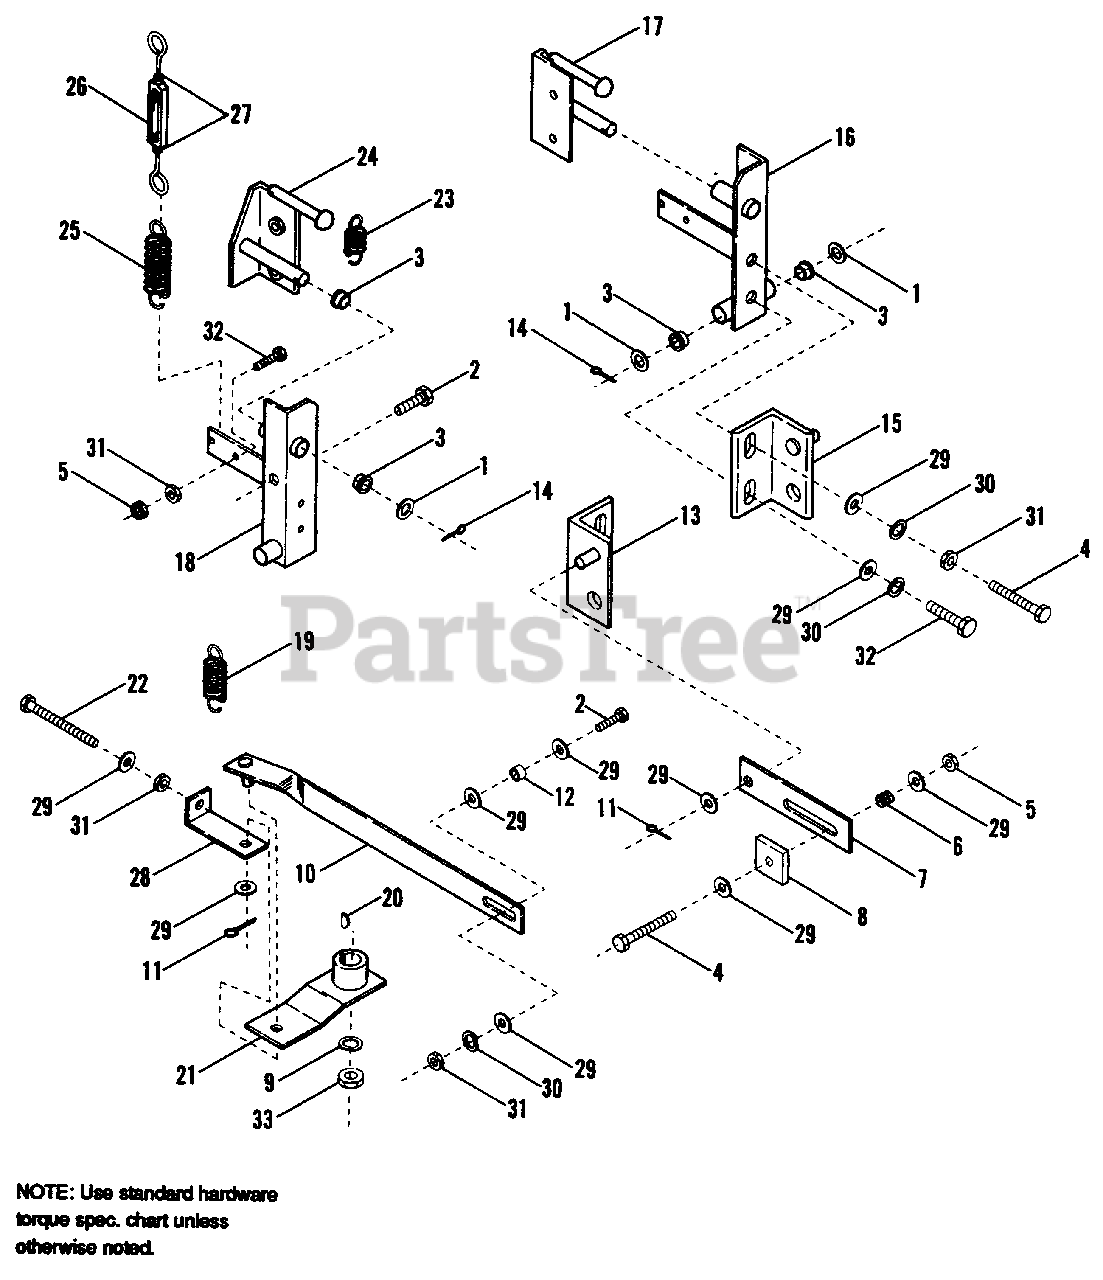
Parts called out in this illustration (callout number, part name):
1	WASHER, Plain
2	CAPSCREW, Hex 5/16-18 x 1-1/4
3	BEARING, Flanged
4	CAPSCREW, Hex Head 5/16-18 x 2 G5
5	LOCKNUT, Unitorque 5/16-18
6	SPRING, Friction
7	BAR, Friction
8	PAD, Friction
9	NUT, Hex 3/8-16
10	LINK ASSY., Control
13	BRACKET ASSY., Speed Adjust, Right Hand
15	BRACKET ASSY., Speed Adjust, Left Hand
16	CONTROL ASSY., Left Hand
17	JOINT ASSY., Left Hand
18	CONTROL ASSY., Right Hand
19	SPRING, Lower
20	KEY, Woodruff 1/8 x 1/2
21	ARM ASSY., Control
22	CAPSCREW, Hex 5/16-18 x 2-1/2
23	SPRING, Handle
24	JOINT ASSY., Right Hand
25	SPRING, Upper
26	TURNBUCKLE
27	NUT, Hex 1/4-20
28	STOP ASSY., Forward Travel
29	WASHER, Plain
30	LOCKWASHER, Spring 5/16
31	NUT, Hex 5/16-18
32	CAPSCREW, Hex 5/16-18 x 1
33	LOCKWASHER, Spring 3/8
